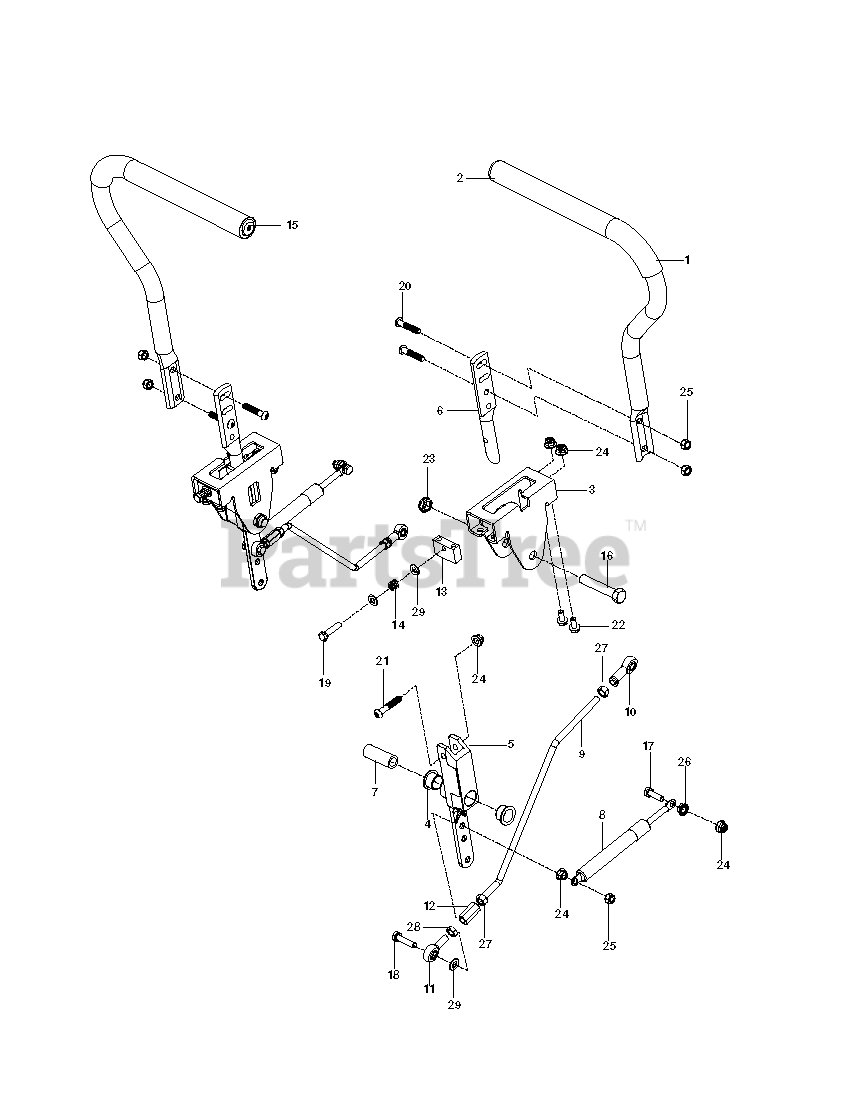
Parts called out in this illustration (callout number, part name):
2	GRIP, FOAM (GROUND) 15
3	BRACKET, CONTROL
4	BEARING, FLANGE
5	LEVER CONTROL PIVOT
7	SPACER, PIVOT CONTROL
8	DAMPENER
10	RH ROD END
11	ROD END LH
12	ROD END COUPLER
12	HCS 1/2C X 2 3/4
13	BLOCK, TRACKING
15	END PLUG 15/16` (BLACK)
16	HCS 1/2C X 2 3/4
17	HCS 5/16C X 1
18	HCS 5/16-18X1-3/4 TPBLT
19	CAPSCREW 5/16 X 1/1/2 HEX HEAD
20	SCREW 5/16-18 X 1 BTN-HD
22	HHFS 5/16-18 X 3/4
23	NUT 1/2-13 HEX JM NYL
24	5/16-18 NYLOC FLANGE NUT
25	NUT 5/16 NYLOC
26	NUT 5/16C WHIZ
27	NUT 5/16F
28	NUT 5/16F LEFTHAND
29	FLAT WASHER 5/16 SAE
